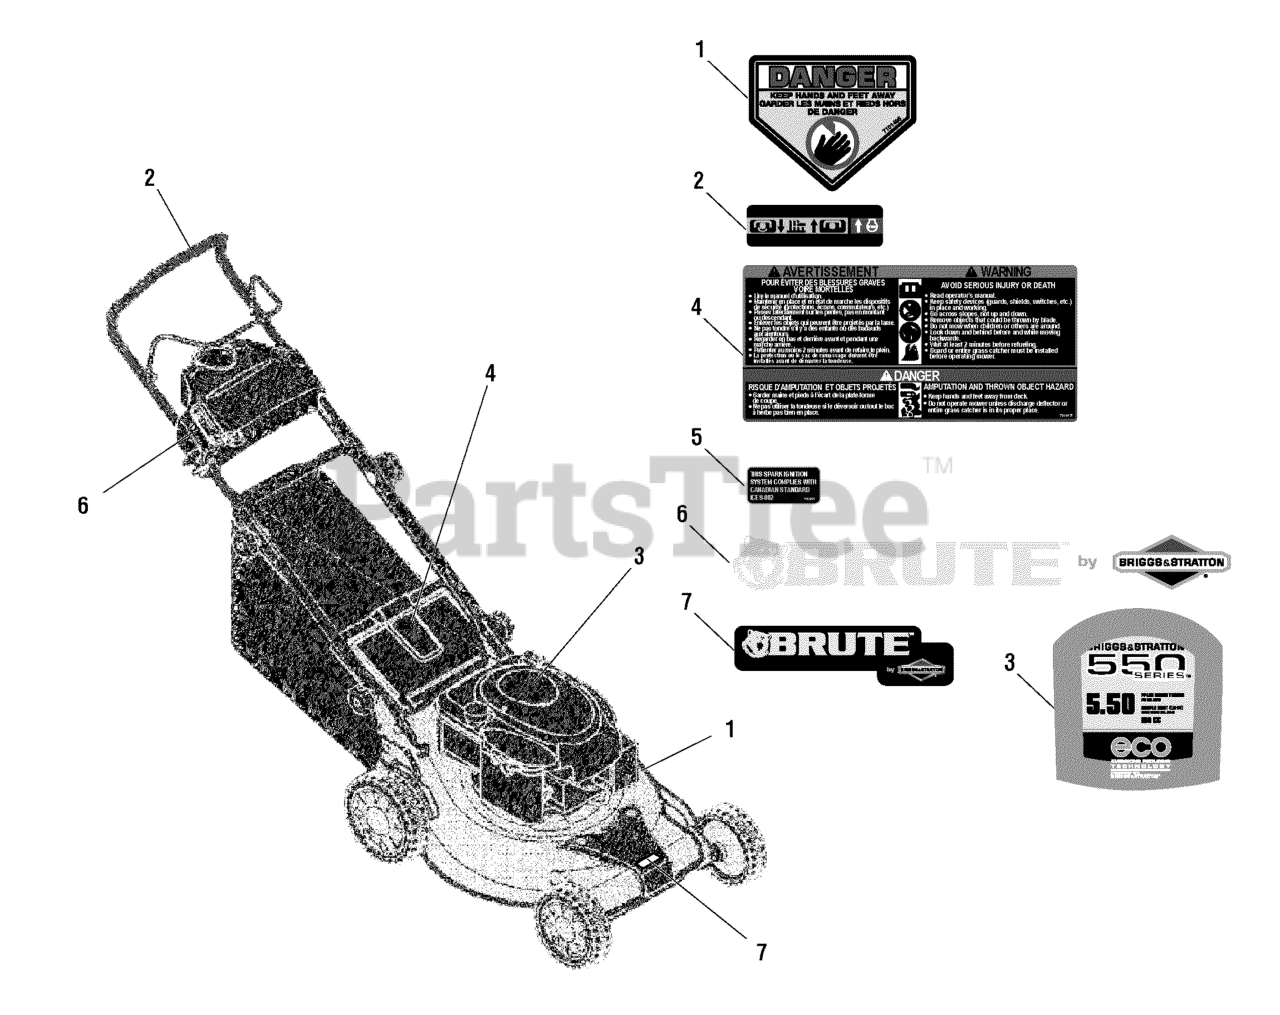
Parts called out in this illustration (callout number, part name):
1	DECAL, CPSC, Danger, French / English
2	DECAL, Instruction, Engine Lever
3	DECAL, Engine 550 XAQ
4	DECAL, French / English, Safety
5	DECAL, Compliance, ICES
6	DECAL, Brute Logo, 12"
7	DECAL, Brute Logo
